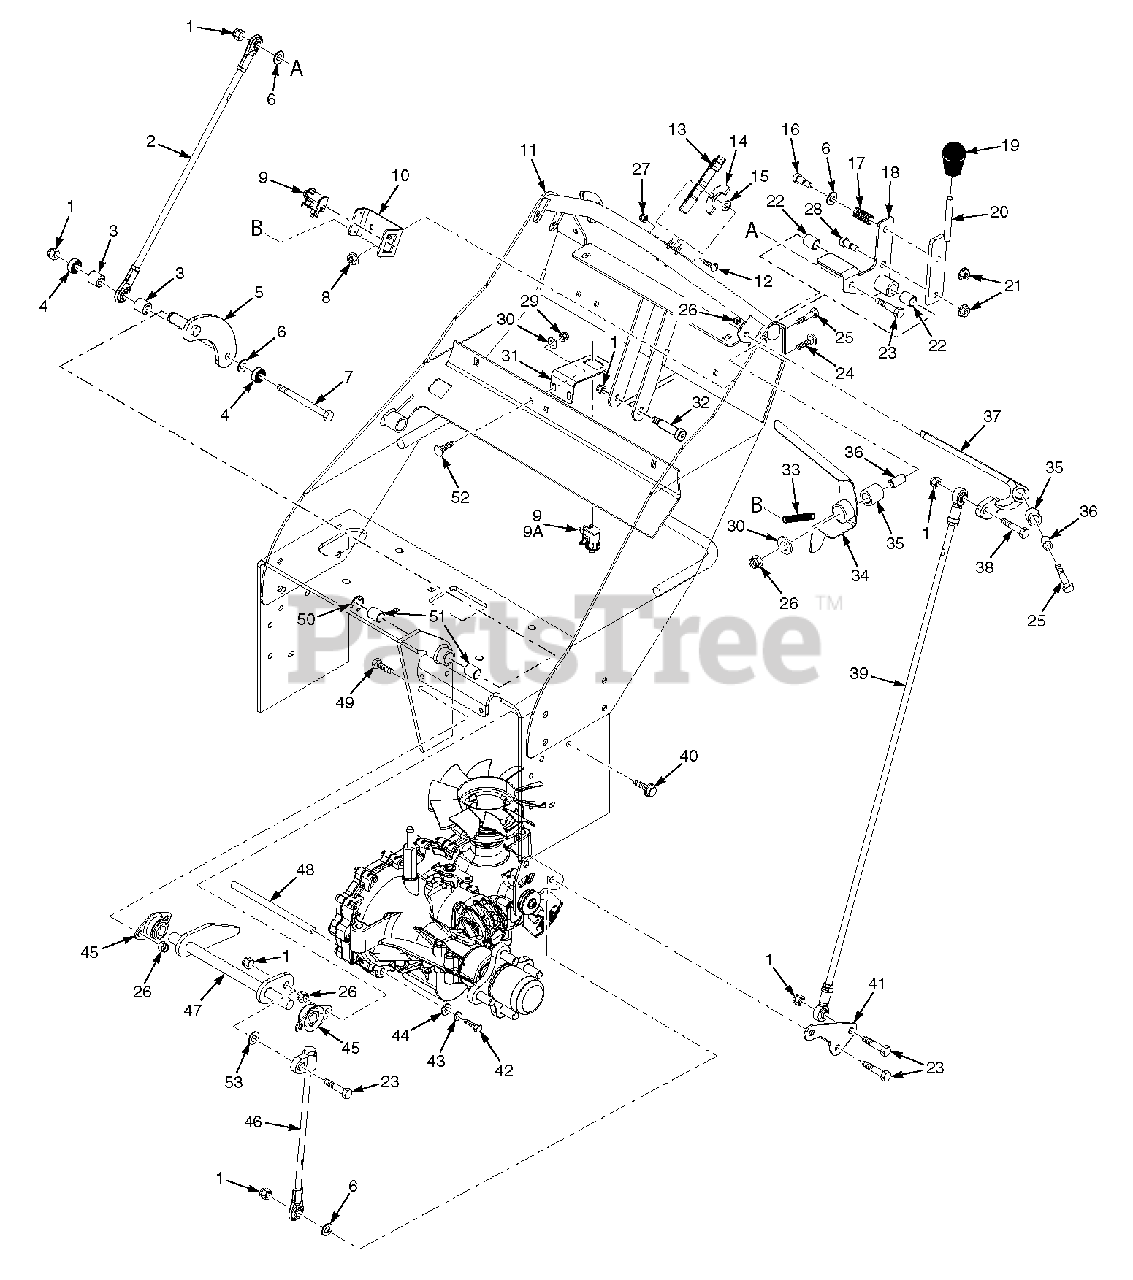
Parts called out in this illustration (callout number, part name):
1	Nut, Elastic Stop 3/8-16
2	Linkage, Speed Control
3	Spacer
4	Bearing
5	Neutral Plate Weldment
6	Flatwasher, 3/8-.406 x .812 x .065
7	Bolt, Hex Head 3/8-16 x 3-1/2"
8	Nut, Serrated Flange 1/4-20
9	Switch (Manual Start)
9A	Switch (Electric Start Only)
10	Bracket, Operator Presence Switch
11	Handle Assy, W/Decals
12	Machine Screw, #10-32 x 1-1/4", Pan Head
13	Latch, Thumb
14	Plate, Anti-Friction
15	Washer, 1/4" Curved Spring
16	Bolt, Shoulder 3/8 x 1"
17	Spring, Speed Control
18	Neutral Handle Assy
19	Knob, Soft Touch
20	Handle Weldment, Speed Control
21	Nut, Serrated Flange 5/16-18
22	Bearing, Plastic 1/2" I.D.
23	Bolt, Hex Head 3/8-16 x 1-1/2"
24	Bolt, Carriage 1/4-20 x 1-1/4"
25	Bolt, Hex Head 5/16-18 x 1-3/4"
26	Nut, Elastic Stop 5/16-18
27	Nut, Elastic Stop #10-32
28	Bolt, Shoulder 3/8 x .375"
29	Nut, Elastic Stop 1/4-20
30	Flatwasher, 5/16-.375 x .875 x .083
30	Bracket, Neutral Switch (Manual Start)
31	Bracket, Neutral Switch (Electric Start Only)
32	Bolt, Shoulder 1/2 x 2"
33	Spring, Operator Presence
34	Handle, Op. Presence-LH
34	Handle, Op. Presence-RH
35	Bearing
36	Sleeve, Pivot
37	Handle Assembly-LH
37	Handle Assembly-RH
38	Bolt, Hex Head 3/8-16 x 1-3/4"
39	Linkage, Steering
40	Cpscrw, 5/16-18 x 3/4"Serrated Flange HH
41	Bracket, Transaxle Control
42	Bolt, Hex Head 3/8-16 x 2"
43	Lockwasher, 3/8" Spring
44	Flatwasher, 3/8-.391 x .938 x .105
45	Bearing, Self Aligning 5/8" I.D.
46	Linkage, Pump
47	Weldment, Bellcrank-LH
47	Weldment, Bellcrank-RH
48	Spacer, Axles
49	Bolt, Hex Head 5/16-18 x 1"
50	Retaining Ring .625" EXT. "E"
51	Bearing
52	Bolt, Carriage 1/4-20 x 3/4"
53	Flatwasher, 3/8-.391 x .938 x .105 Hardened
